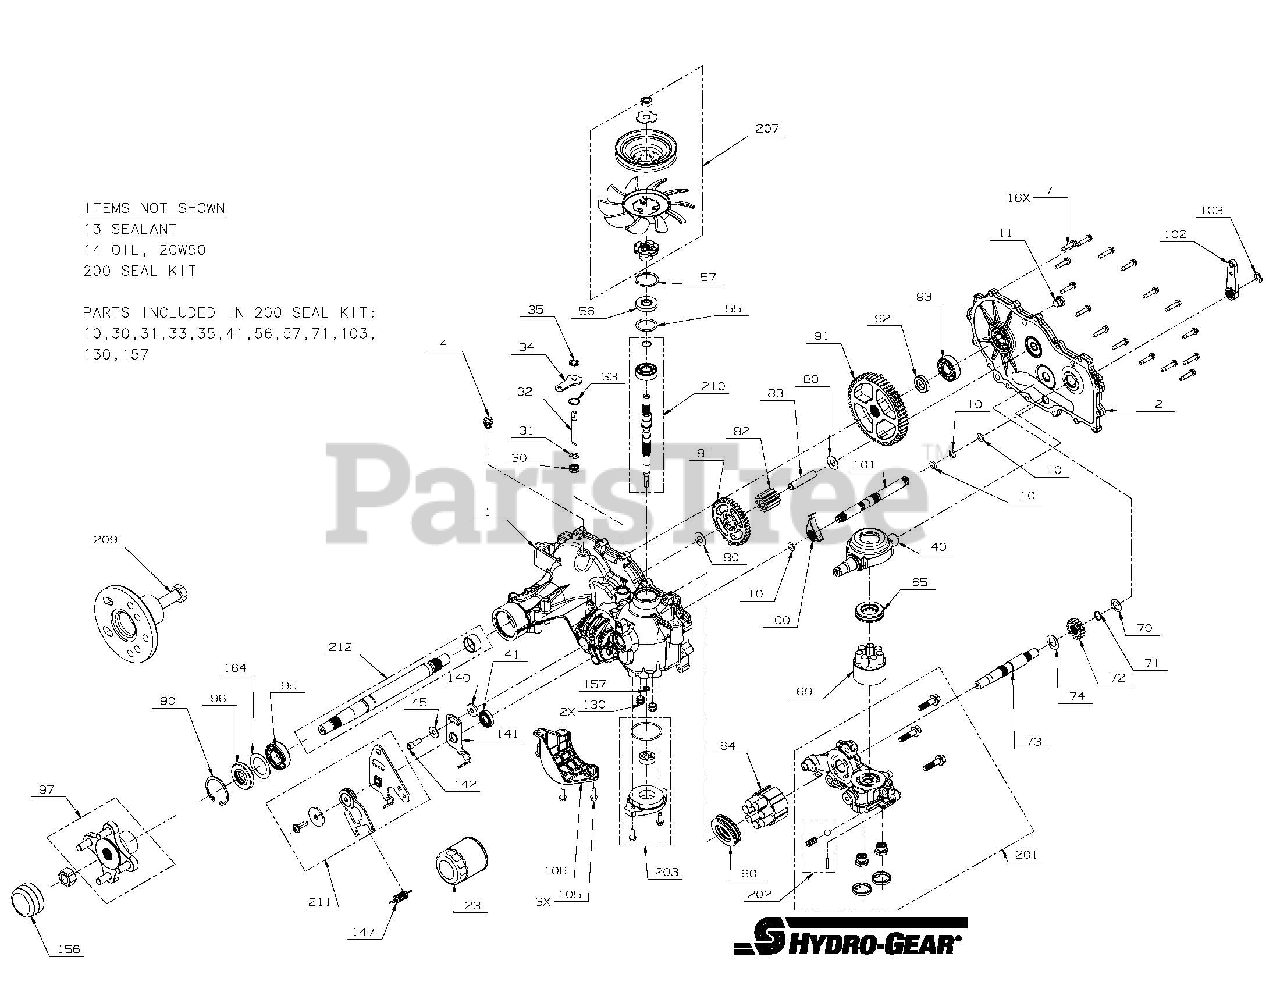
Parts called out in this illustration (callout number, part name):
7	SCREW, HEX WASHER
13	TUBE, SEALANT
23	FILTER, SPIN-ON 2.6 X 3.0
30	SEAL, LIP .375 X .75 X .25
31	RING, RETAINING EXTERNAL .375
33	RING, RETAINING .750, INTERNAL
34	ARM, BYPASS
35	RING, RETAINING .375 EXTERNAL
40	SWASHPLA1E, TRUNNION
41	SEAL, LIP 18 X 32 X 7
45	WASHER FLA1.34 X .88 X .06
55	WASHER, FLAT 1.23 X 1.57 X .04
56	SEAL, LIP 17 x 40 x 7
57	RING RETAINING INTERNAL
60	BEARING, THRUST 35 x 62 x 18
64	KIT, 16cc CYLINDER BLOCK ASSEMBLY
65	BEARING, THRUST 30 x 52 x 13
69	KIT, BLOCK 7 PISTON
70	WASHER, .63 X 1.00 X .05 FLAT
71	RETAINING RING, MOTOR SHAFT
74	WASHER, .71 X 1.16 X .04 FLAT
80	WASHER, .51 X 1.00 X .03 FLAT
83	PIN, JACKSHAFT
90	RING, RETAINING 2.25 INTERNAL
95	BEARING, BALL 6205R-1 25.4 x 52 x 15
96	SEAL, LIP, TC4, 1.0 X 2.06 X .38
105	SCREW, HEX WASHER 1/4-20 X .75
106	GUARD, FILTER, RH
140	SPACER 0.320 ID X 1.005 OD X 0.1495 THK
141	ARM, NEUTRAL RIGHT
142	SHCS 5/16-24 x 7/8 (W/PATCH)
147	SPRING, EXTENSION
200	KIT, SEAL, ZT-2800
203	KIT, CHARGE
207	KIT, FAN/PULLEY
209	KIT, HUB PULLER
210	KIT, INPUT SHAFT
